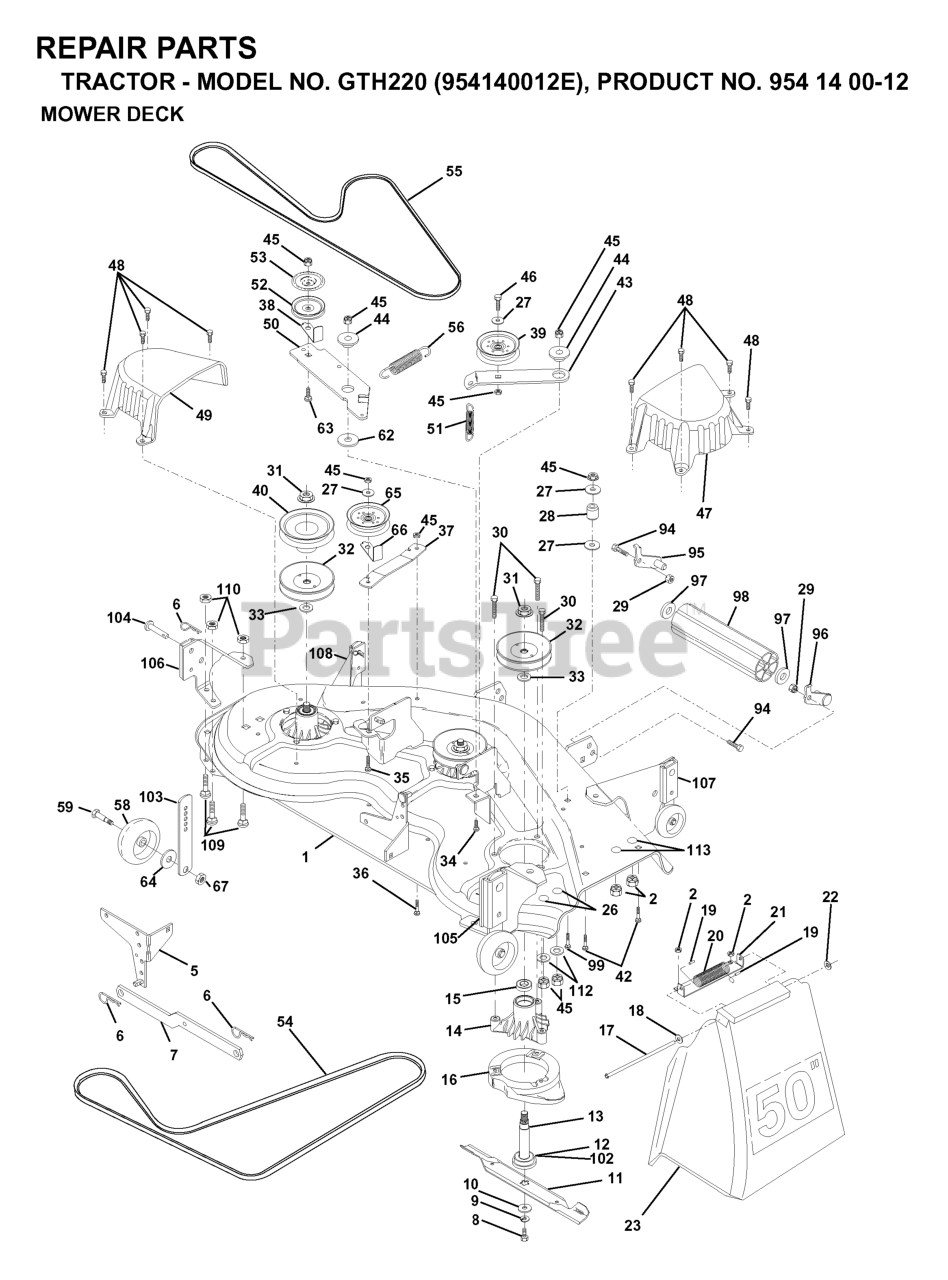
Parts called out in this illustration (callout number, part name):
2	LOCKNUT
5	BRACKET SWAY BAR
6	RETAINER-SPRNG RB
7	REAR SUSP ARM
8	BLADE BOLT
9	LOCKWASHER
10	WASHER.BLADE
11	BLADE.50".HI-LIFT
12	BEARING.BALL.#6204.(MANDREL)
13	SHAFT.ASM.W/BEARING
14	HOUSING.MANDREL.44/46" VENT
16	STRIPPER
17	ROD-HINGE T
18	Washer 11/32 x 5/8 x 16 Ga SD
19	CAP-SLEEVE LT
20	SPRING TORSION
21	BRACKET, DEFLECTOR
22	NUT PUSH M
23	SHIELD.DEFLECTOR.MOWER.50"BLK.
27	WASHER
28	IDLER SPRING SPACER
29	NUT
30	SCREW THDROL ROLLING WASHER HD
31	NUT
32	PULLEY/MANDREL
33	WASHER
34	BOLT.3/8-14X1.25
36	BOLT D
37	STIFFENER ARM
38	KEEPER, BELT IDLER
39	FLAT IDLER PULLEY
40	PULLEY.DRIVEN.44"
42	RP BOLT 5/16-18 X3/4 ZN/YEL GR
43	ARM.IDLER.SEC.44"
44	SPACER RETAINER
46	BOLT
47	COVER MANDRELL
48	SCREW.1/4-20X5/8
49	COVER.MANDREL.LH.44"
50	ARM.IDLER.PRIMARY
51	SPRING.SEC.44"VEN
52	PULLEY IDLER
53	SHIELD IDLER
54	V-BELT.PRMRY 46/50 VENT.BLK BK
55	BELT V SECONDARY
58	WHEEL GAGE DONUT
59	BOLT, SHOULDER
62	HARDENED WASHER
63	BOLT.3/8-16X1.50
64	WASHER.5/16.FLAT.STE.STD.
67	LOCKNUT
94	BOLT
95	BRACKET LH (A)
96	BRACKET RH (B)
97	Washer 1 17/32 X 7/8 X 16 Ga
98	NOSE ROLLER
102	WASHER FELT
103	BAR.ADJUST.WHEEL.ANTI.SCALP.BL
104	RIVET.PIN.HEAD.YELLOW.
112	WASHER
113	BOLT.CARR.5/16-18X1/2
